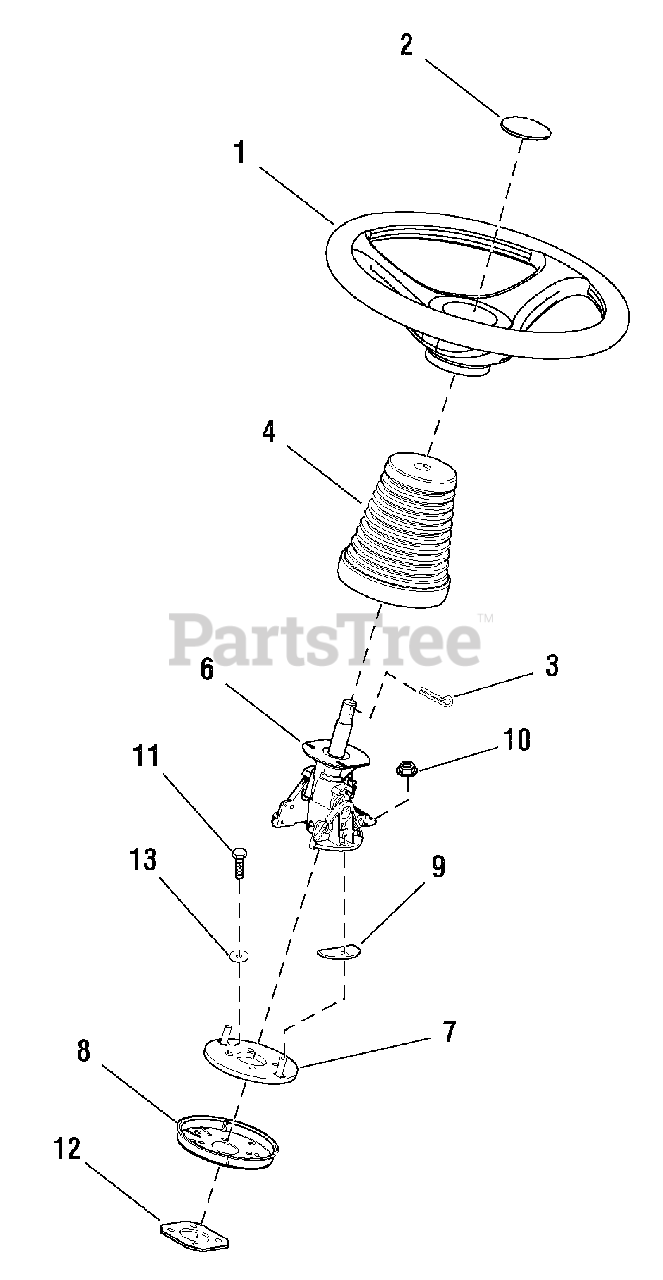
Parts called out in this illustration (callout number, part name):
1	STEERING WHEEL
2	CAP, Steering Wheel
4	BELLOWS
6	TILT STEERING
7	PLATE, Steering
8	MOUNT PLATE
9	SPACER, Flat
10	NUT, Hex Keps, 5/16-18
11	CAPSCREW, M6-1x30
12	MOUNT PLATE
13	WASHER, Lock
